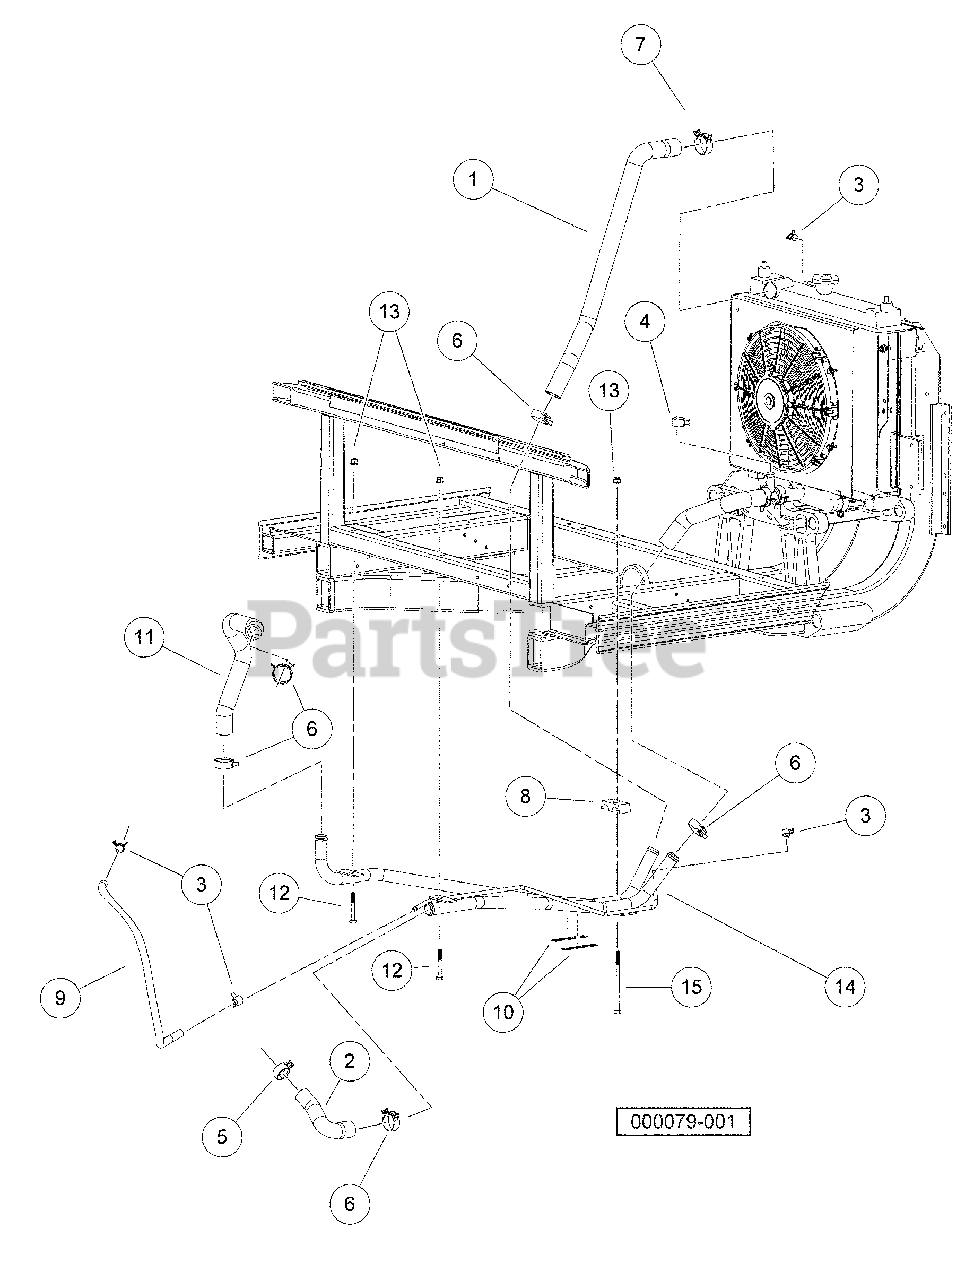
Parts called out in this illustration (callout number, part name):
1	Hose, Coolant Upper Rad
2	Hose, Coolant Lower Eng
3	Clamp, Hose, CTB 15mm
4	Clamp, Hose, CTB 22mm
5	Clamp, Hose, Ctb 30mm
6	Clamp, Hose, Ctb 35mm
7	Clamp, Hose, Ctb 38mm
8	Clamp, Bar
9	Hose, Vent Tube To Eng, Coolnt
10	Decal, Hot Surface Warning
11	Hose, Coolant, Return, Engine
12	Bolt Flanged Head, M8 X 1.25 X 65
13	Lock Nut, Flg M8 X 1.25 Nylon
14	Weldment, Group, Coolant Pipe
15	Pipe, Coolant Upper
16	Pipe, Coolant Lower
17	Tab, Rear Mntg, Coolant Pipe
18	Pipe, Vent, Coolant
19	Tab, Cooling Pipe Mount
20	Bolt, M8 X 1.25 X 130
